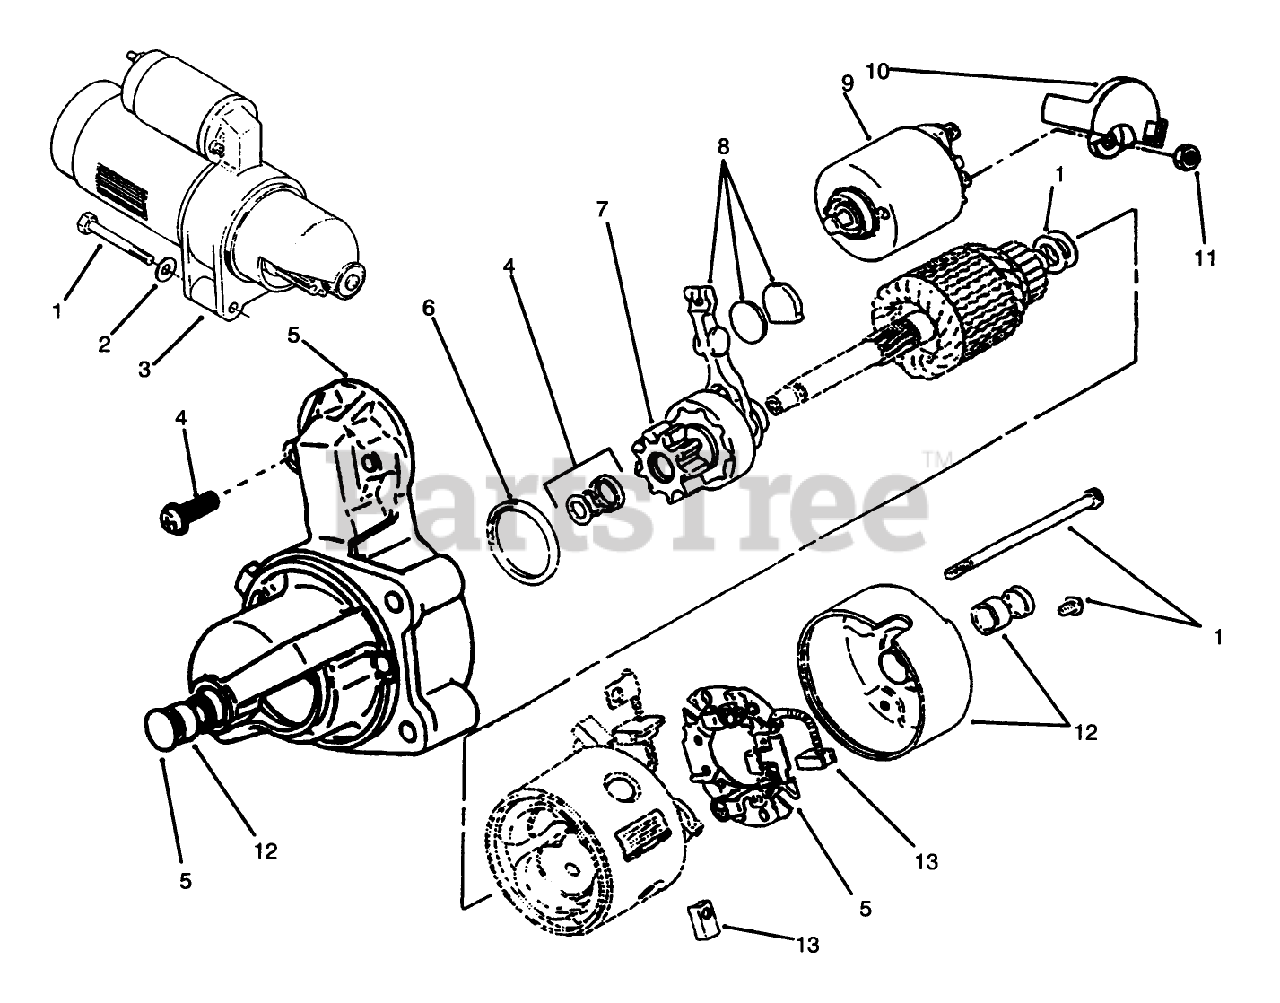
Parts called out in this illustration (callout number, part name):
2	WASHER
5	KIT-MTG BRKT
7	CLUTCH STARTER ASSEMBLY
9	STARTER SOLENOID KIT
11	O-RING
